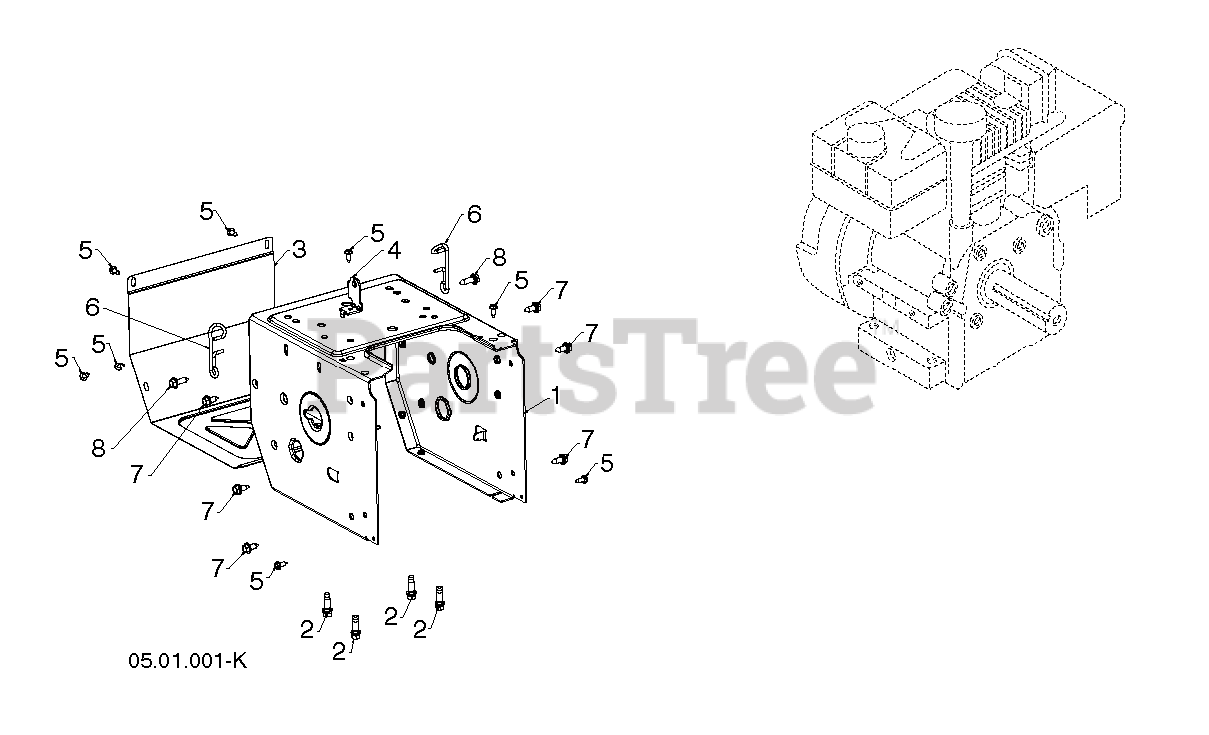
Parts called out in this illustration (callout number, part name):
1	FRAME MS 668
2	BOLT 3/8-16X1-1/8
3	COVER COVER.FRAME MS668 ORANGE
4	BRACKET.SHIFTER.BZP
5	SCREW.HEX HEAD W/COLLAR 1/4-20
6	WIREFORM.SUPPORT.CABLE
7	BOLT.HEX.HD.WASHER.5/16-18X.75
8	SCREW HEX_SERR_HD_5_16-18X1.0
